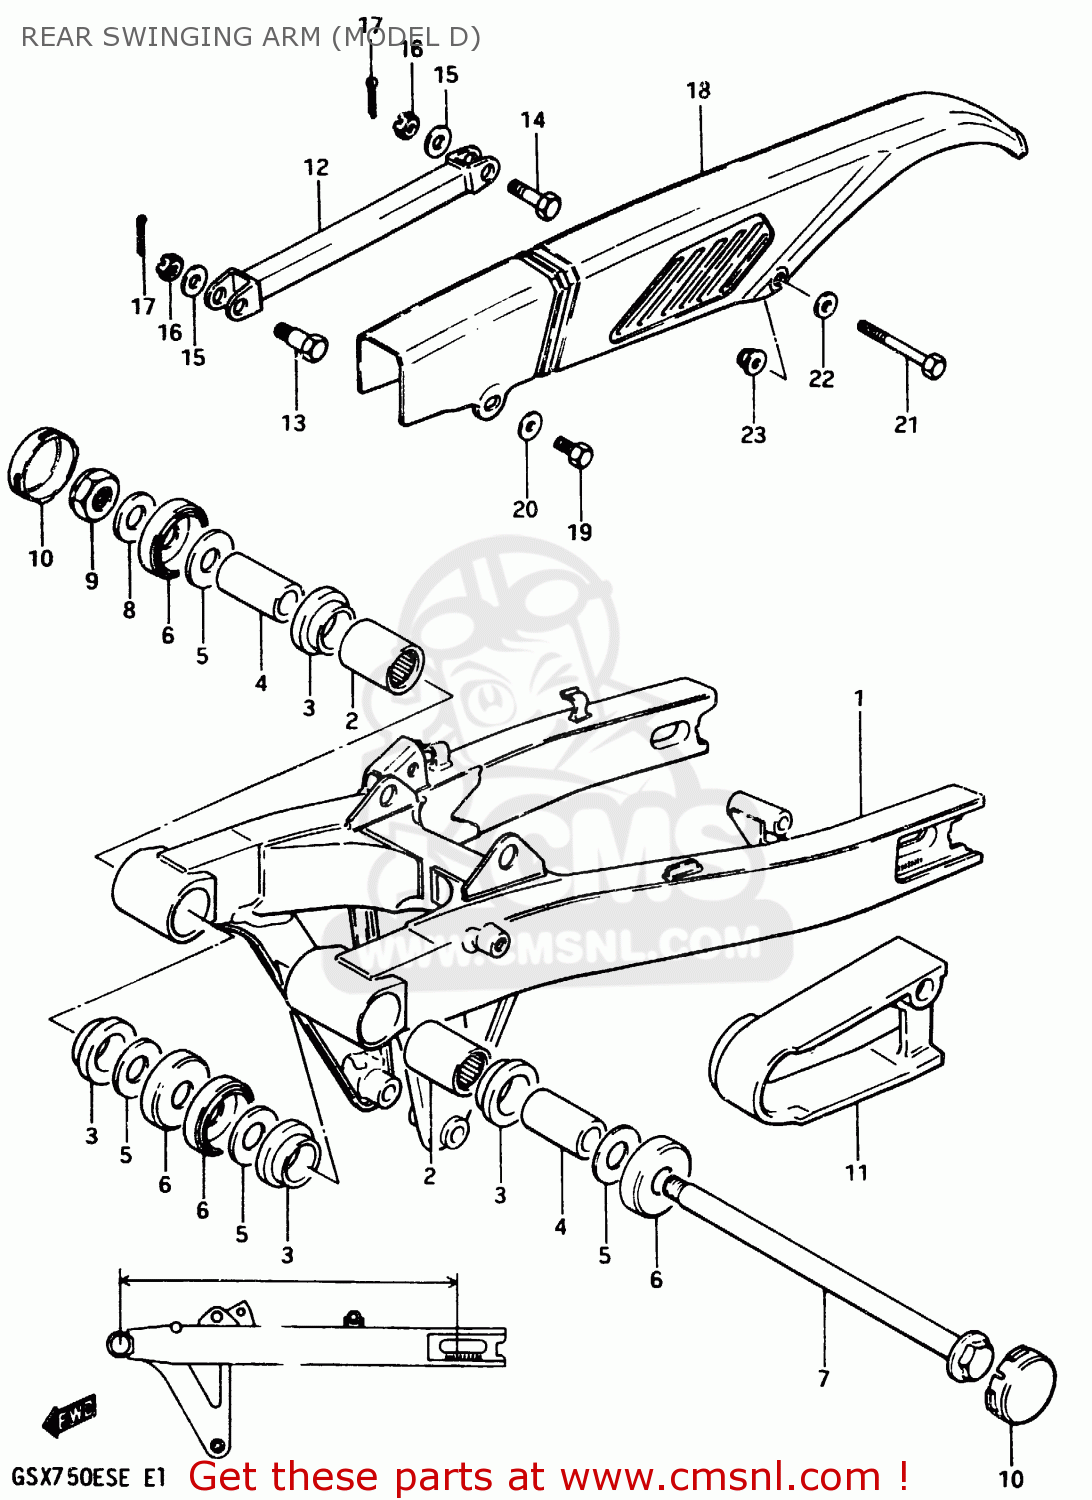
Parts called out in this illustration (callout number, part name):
1	SWINGING ARM SET
2	BEARING(25X33X30)
3	BUSHING
4	SPACER,RR SWGARM PIVOT
5	WASHER
6	COVER,RR SWINGINGARM PIVOT
7	SHAFT,REAR SWING ARM
8	WASHER
9	NUT
10	CAP,PIVOT
11	BUFFER,CHAIN TOUCH DEFLECTOR
12	TORQUE LINK,REAR
13	BOLT
14	BOLT(10X39)
15	WASHER
16	NUT
17	PIN 20X20
18	CASE,CHAIN
19	BOLT
20	WASHER
21	BOLT 6X60
22	WASHER (6.5X18X1.6)
23	NUT 6MM
